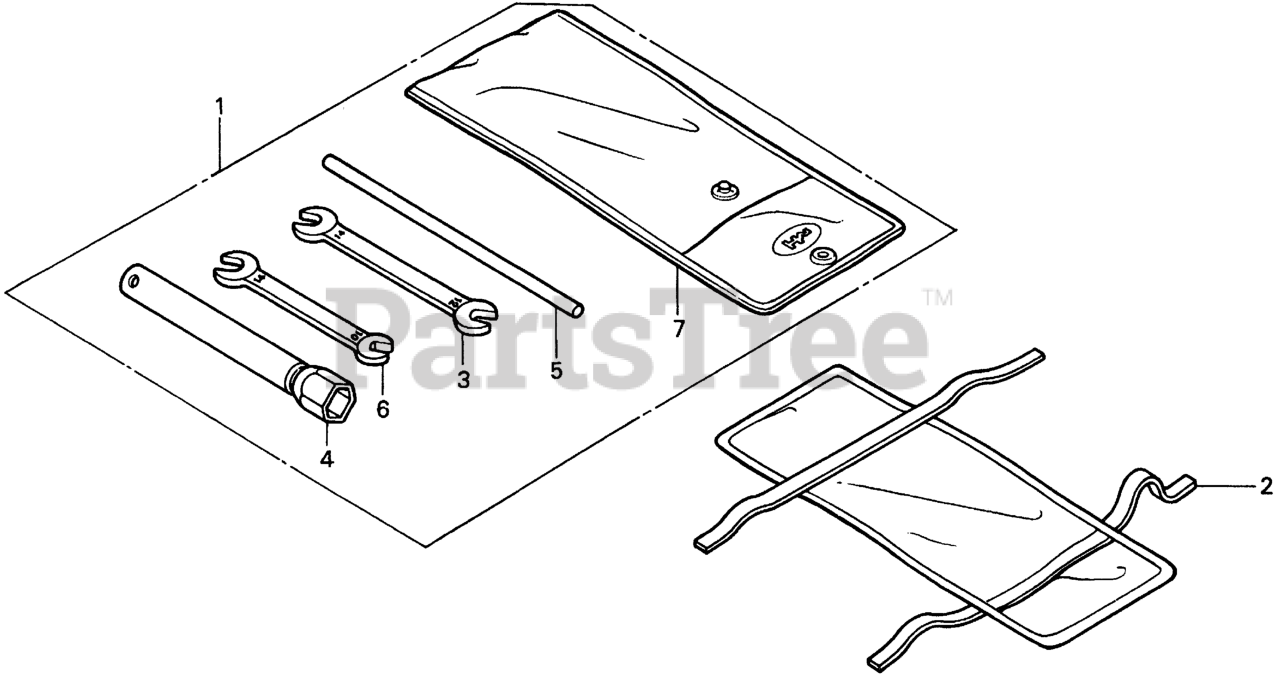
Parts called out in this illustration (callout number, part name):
3	SPANNER (12X14)
4	WRENCH, SPARK PLUG (NOT AVAILABLE)
5	HANDLE, BOX WRENCH (NOT AVAILABLE)
6	WRENCH (10X14) (OPEN END)
7	BAG, TOOL
